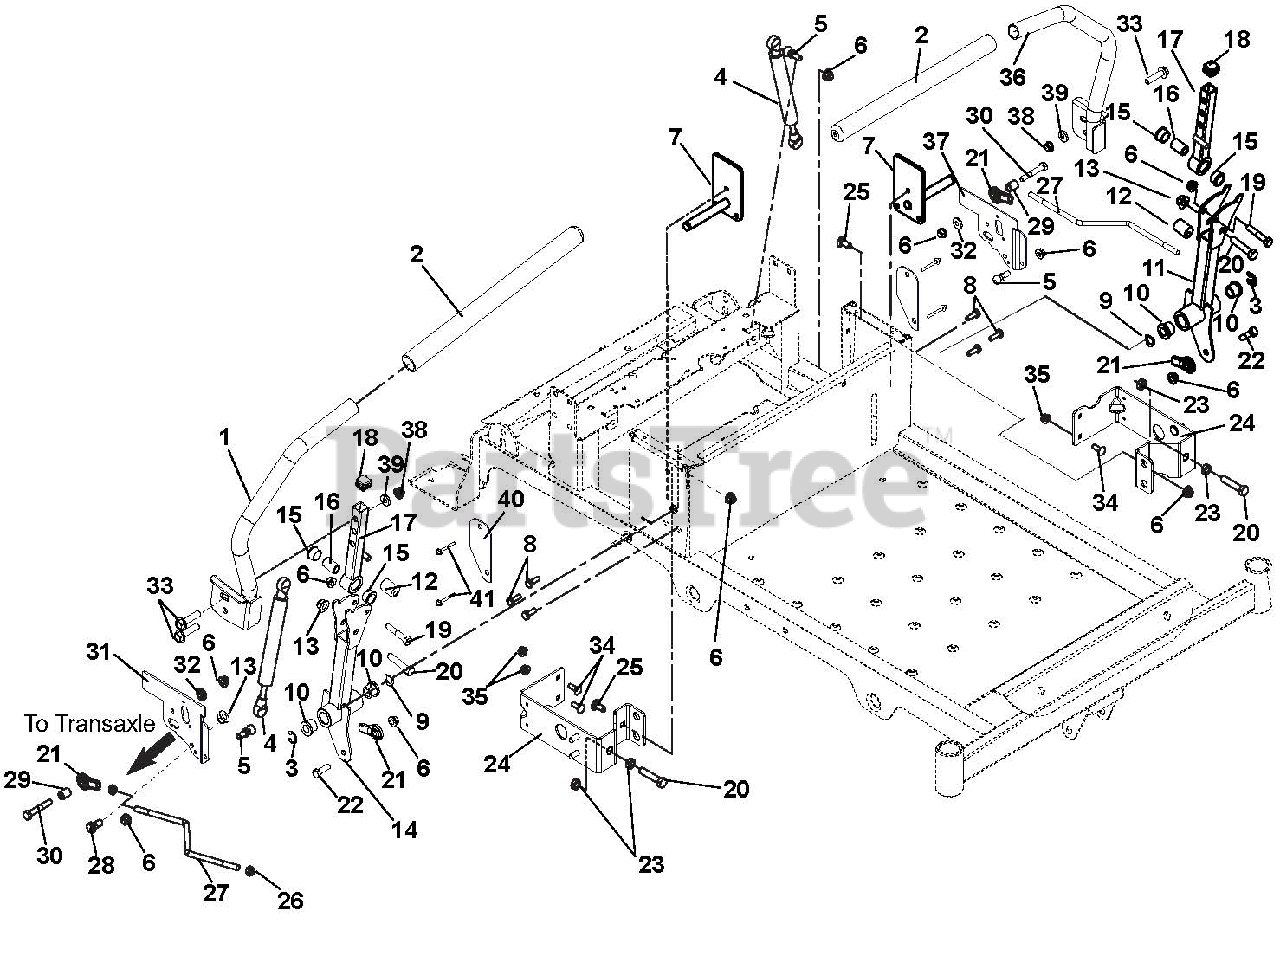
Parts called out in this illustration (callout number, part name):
1	WMT, STEERING HANDLE
2	GRIP, HANDLEBAR 15" FOAM
3	RG-RTNG-EXT .500X.042 (E)
4	DAMPER, STABILUS
5	STUD- BALL
6	@NUT-LK-NYL-FLG .31-18 YWZC
7	WMT, STEERING SHAFT
8	SCR-TAP .25-20X.50 HWH TR YWZ
9	WSHR-WAVE .50X.75X.015 .13FRHT
10	BSHG-FLG .500X.750X.625X.937
11	WMT, LOWER CONTROL ARM
12	BSHG, ECCENTRIC .328X.750X.970
13	@NUT-LK-NYL-FLG .38-16 YWZC
14	WMT, LOWER CONTROL RH
15	BSHG-FLG, .625X.75X.450X.875
16	SPACER, .375X.625X.970 (PM)
17	WMT, UPPER CONTROL ARM
18	CAP PLUG, SQ 3/4-14-20 RIBBED
19	@BLT-HEX .31-18X1.75 GR5 YWZC
20	BLT-HEX .375-16X1.750 FTD YWZC
21	ALIGNABALL, 5/16 RH THREAD
22	@BLT-HEX .31-18X1.00 GR5 YWZC
23	NUT-HEX-JAM .375-16 YWZC
24	WMT, STEERING STOP
25	@BLT-RHDSSQNK .31-18X.75 G5YZ
26	NUT-JAM .31-24 YWZC
27	WIREFORM, STEERING LINK
28	@BLT-HEX .38-16X.75 GR5 YWZC
29	SPACER, .328X.500X.625
30	@BLT-HEX .31-18X2.00 GR5 YWZC
31	PLATE, DAMPENER (RH)
32	BSHG-FLG .316X.430X.225X.750
33	BLT-SERHFWH .375-16X1.25 YWZC
34	@BLT-RDHDSQNK .25-20X.75 G5YZ
35	@NUT-LK-NYL-FLG .25-20 YWZC
36	WMT, STEERING HANDLE LH
37	PLATE, DAMPENER (LH)
38	@NUT-LK-CTR-JAM .375-16 YWZC
39	@WSHR-FL-STL.406X.812X.065 YWZ
40	GUARD, DAMPENER PLATE
41	RIVET, #66 STEEL POP PD BLACK
